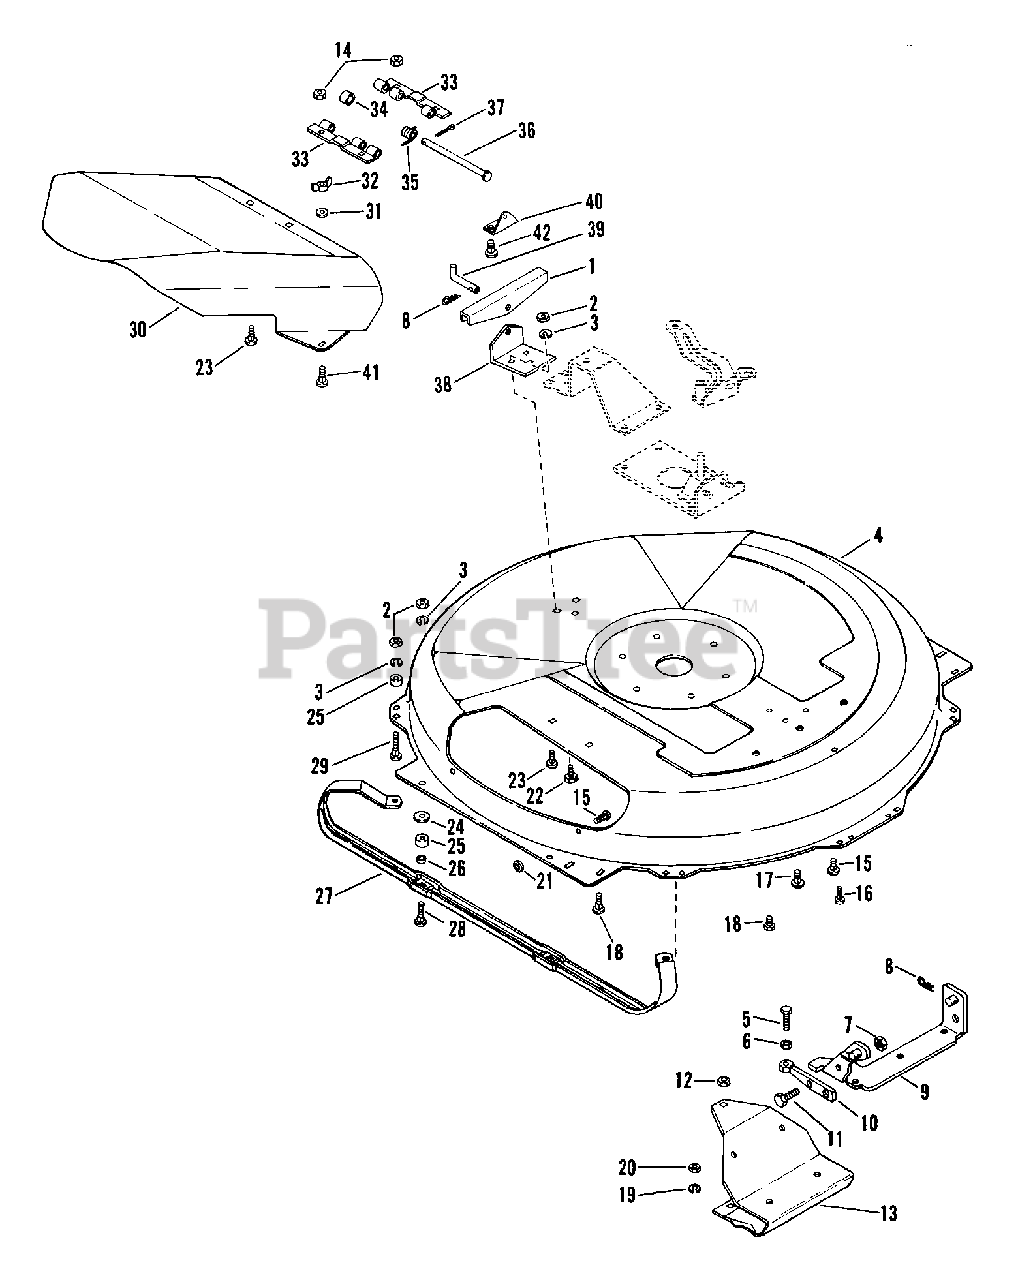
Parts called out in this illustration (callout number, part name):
1	SWIVEL BRACKET
2	NUT-HEX .312-18
3	WSHR-LK .312X.097 PL HVY
4	26 IN MOWER PAN W/ DECALS
4	26" MOWER PAN ASSEMBLY
4	28" MOWER PAN ASSEMBLY
4	30"MOWER PAN W/DEFLECTOR&DECAL
4	30" MOWER PAN ASSEMBLY
4	32 IN MOWER PAN SERVICE ASSEMB
4	32 IN MOWER PAN ASSEMBLY
5	BLT-HEX .38-16X1.25 PL GR5
6	NUT-JAM .375-16 PL
7	NUT-LK-CTR .375-16 GR A PL
8	PIN-HAIR INT .08X.38X1.42 YWZC
9	FRONT BRACKET 26
9	FRONT BRACKET 30"
9	FRONT BRACKET 32"
10	ADJUSTING ARM
11	@BLT-HEX .38-16X.88 PL GR2
12	NUT-LK .312-18 GR A PL
13	SKID -32" MOWER
14	NUT-LK-CTR .250-20 PL
15	BLT-RDHDSQNK .312-18X.62SHTPL
16	BLT-RDHDSQNK .25-20X.75
17	SCR-TAP .375-16X .50 HWH PL TR
18	BLT-RDHDSQNK .31-18X1.00 PL
19	WSHR-LK .250X.077 HVY PL
20	NUT-HEX .250-20 PL
21	NUT-PUSH .312
22	BLT-RDHDSQNK .31-18X.75 GR5 PL
23	BLT-RDHDSQNK .25-20X.62 PL
24	WSHR-FL-STL .328X1.0X.094
25	SPACER .328X.750X.375
26	SPACER BUSHING .5 X .32 X .21
27	28 IN ADJUSTABLE SKID
27	32 IN ADJUSTABLE SKID
28	BLT-RDHDSQNK .31-18X1.25 SHTPL
29	BLT-RDHDSQNK .31-18X1.75 SHTPL
30	PAN CHUTE EXTENSION
30	CHUTE DEFLECTOR
30	DISCHARGE CHUTE
30	DISCHARGE CHUTE W/DECAL
31	WSHR-FL-STL .328X.875X.062 PL
32	NUT-WING .250-20
32	NUT-WING W/INSERT .312 - 18
33	HINGE PLATE
34	BSHG-SLV .334 X .502 X 1.437
35	SG-TORS .095X.50X 1.0
35	SG-TORS .090X.37X.63
36	CLEVIS PIN
37	PIN-COTR .09X.75 PL
38	REAR MOUNTING BRACKET
39	CLEVIS PIN
40	REAR MTG BRACKET
40	REAR MOUNTING BRACKET
41	BLT-RDHDSQNK .25-20X1.00 GR5
42	SCR-TAP .312-18X.50 HWH PL TR
